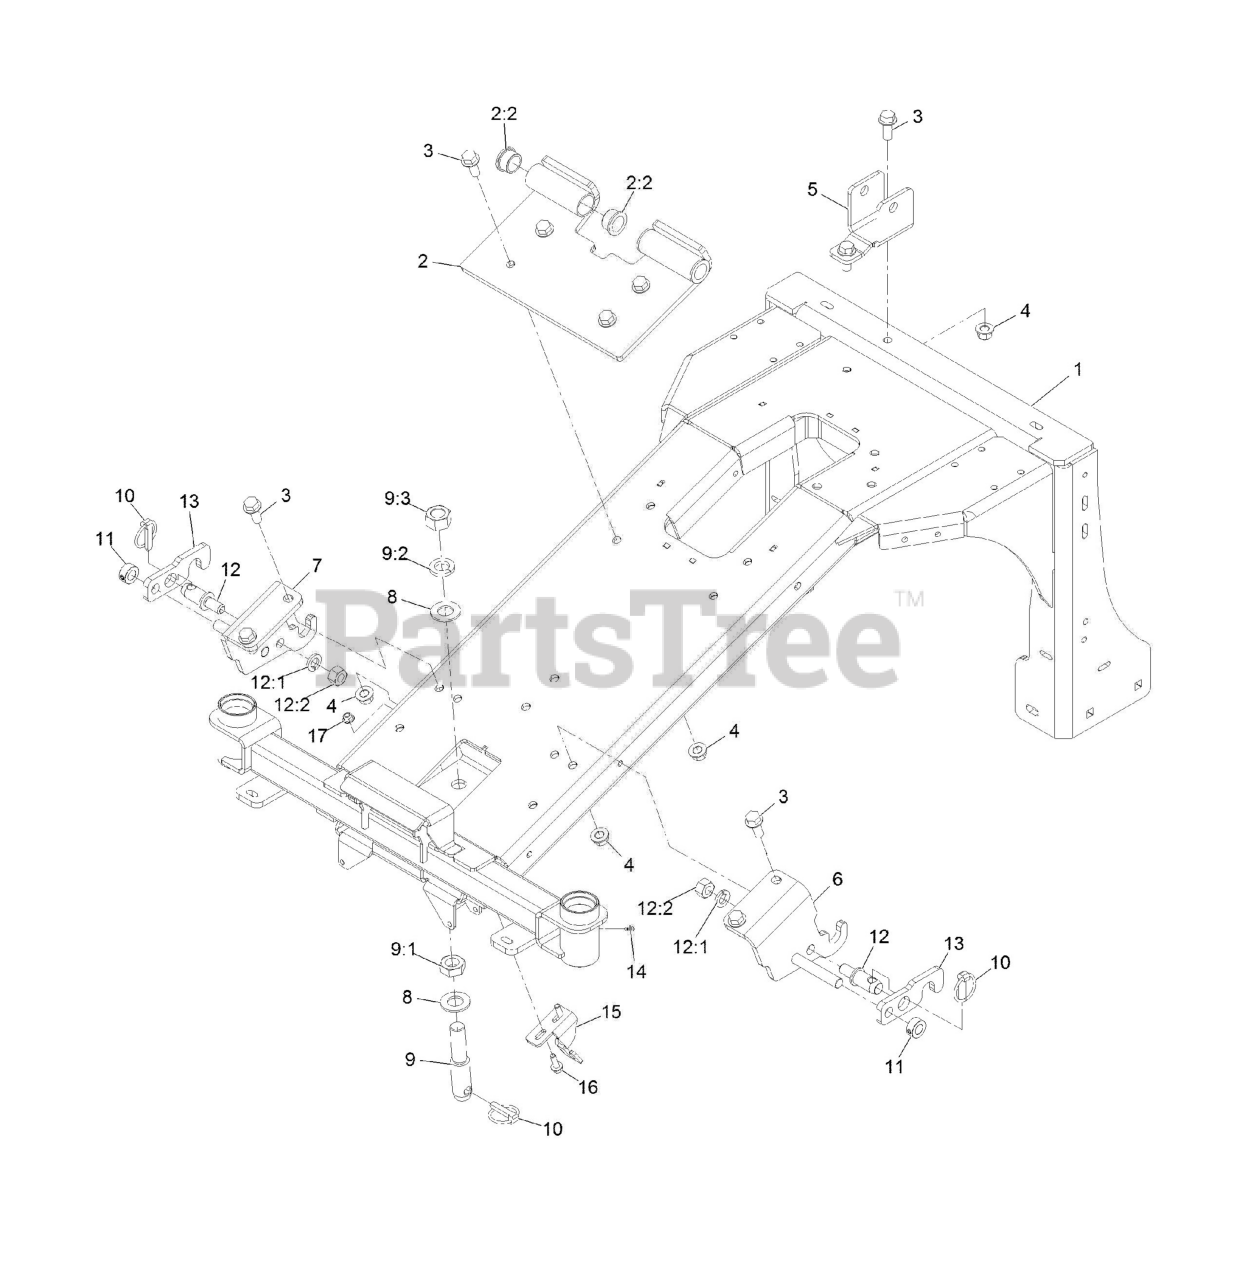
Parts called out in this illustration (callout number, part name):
1	FRONT FRAME ASM
2	PIVOT-ARM, LIFT ASM
2:2	BUSHING-FLANGE
3	SCREW-HHF
4	Nut-Lock 1/2-13
5	BRACKET-MOUNT, CYLINDER
6	X-REF 135-9471-05
7	HITCH PIN-RH
8	WASHER-FLAT
9	1-1/8 X 5-1/4 LIFT ARM PI
9:1	NUT-JAM
9:2	WASHER-LOCK/SP
9:3	NUT-HEX
10	PIN-LYNCH
11	5/8 SHAFT COLLAR
12	7/8 X 3-1/8 ANCHOR PIN (2
12:1	WASHER-LOCK
12:2	NUT-HEX
13	PLATE-ATTACHMENT, LOCK
14	FITTING-GREASE, ZERK
15	BRACKET-CABLE, LCS
16	SCREW-HH
17	NUT-HF, NI
